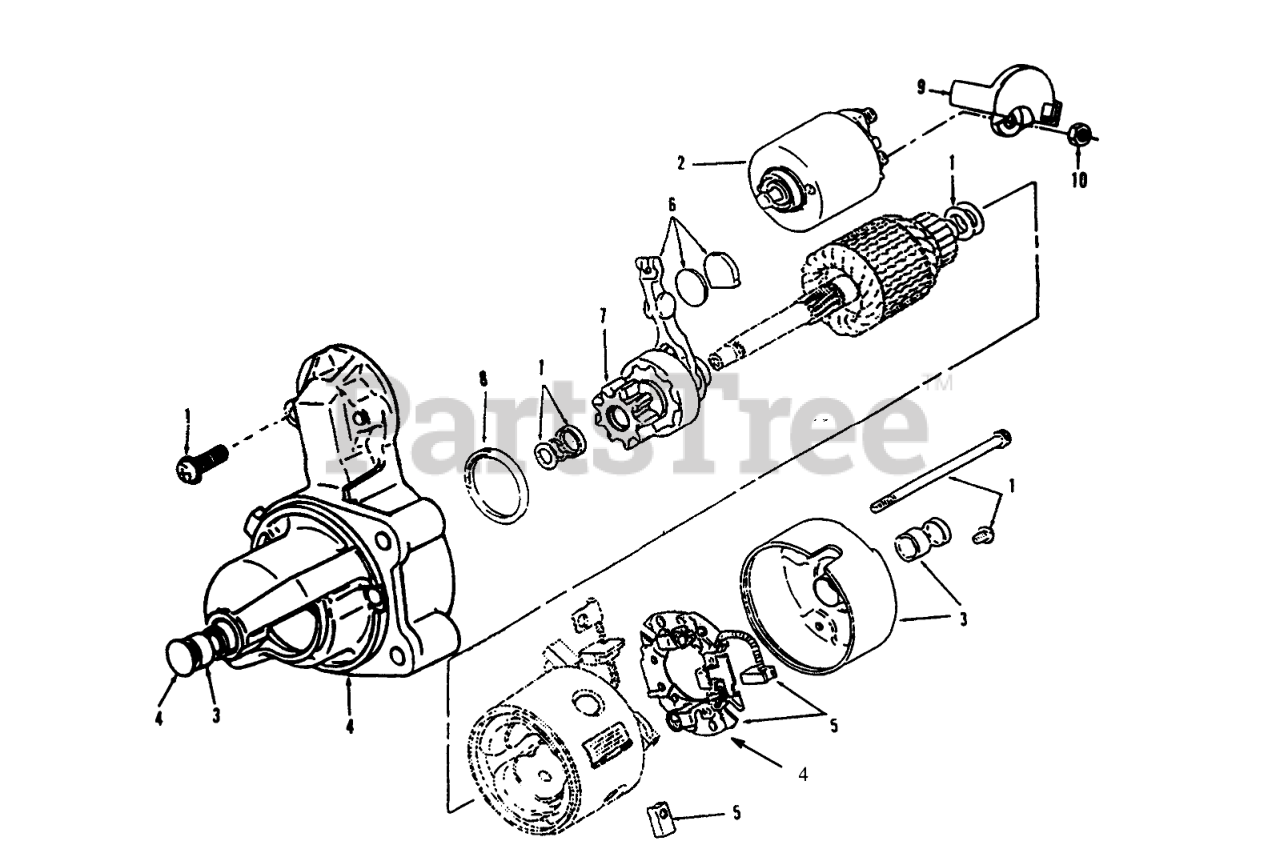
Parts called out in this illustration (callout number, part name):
1	Kit-Hardware, Starter (Includes (2) Solenoid Mtg Screws, 2 Thru Bolts, Armature Shims, Pinion Collar, & Retaining Ring)
2	Kit-Solenoid, Starter (Includes Solenoid & Spring Plunger)
3	Kit-Bushing, Starter (Includes Rear Cap with Bushing & Front Bushing)
4	Kit-Mounting Bracket (Incl. Ref. #5)
5	Kit-Brush, Starter (Includes (2) Negative & (1) Positive Brushes)
6	Kit-Shift Lever, Starter (Includes Lever, Wear Plate & Rubber Plug)
7	Clutch Assembly-Starter (Includes Pinion Gear)
8	Dust Seal
9	Cap-Starter Solenoid
10	Nut-M8
